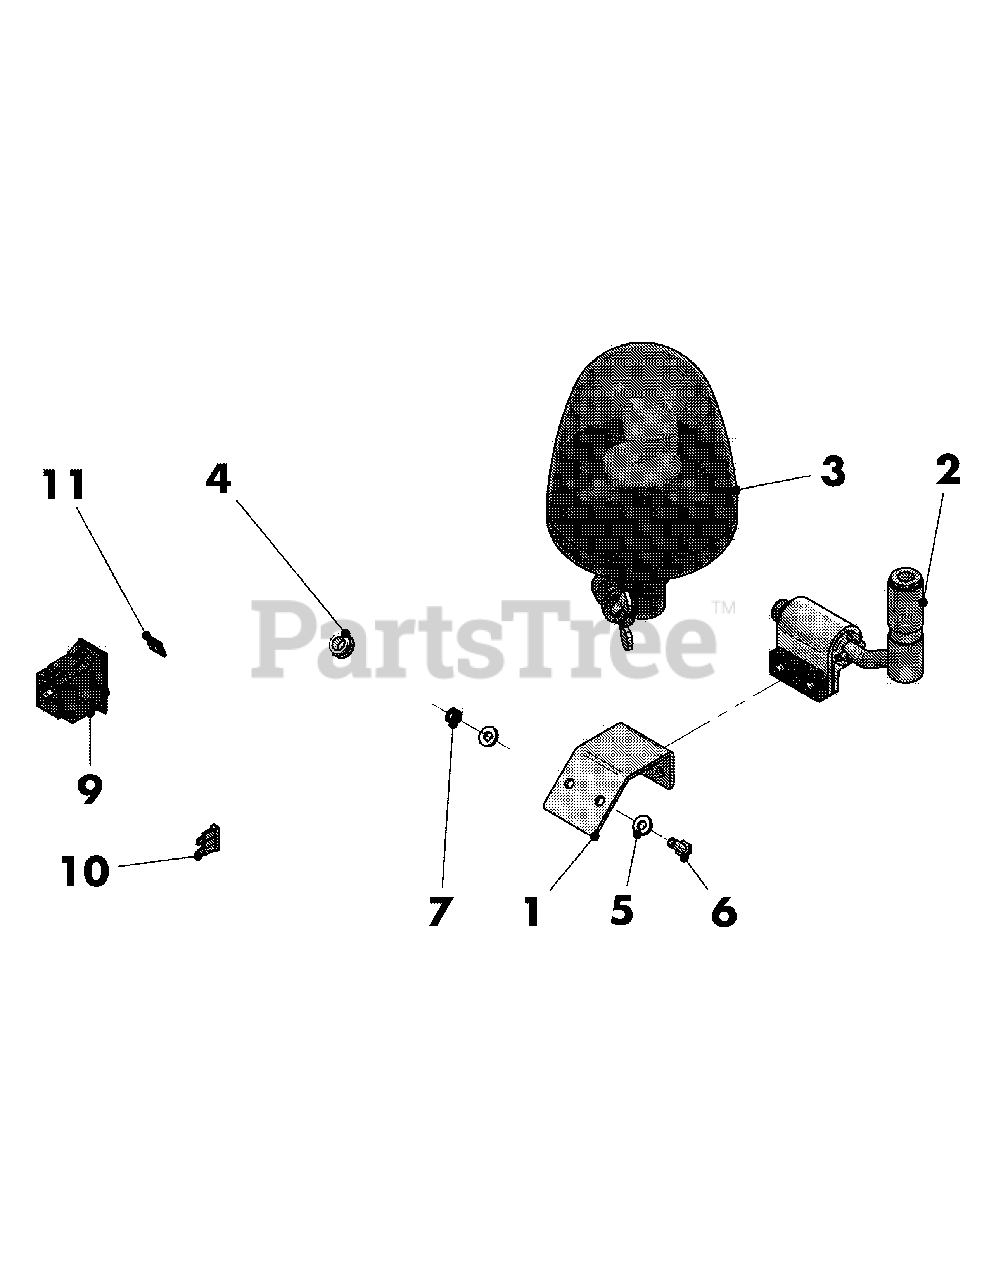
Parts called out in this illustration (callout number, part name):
1	Console - Lamp
2	Console - Beacon LGT
3	Light - Rotating
11	Emblem - Light
